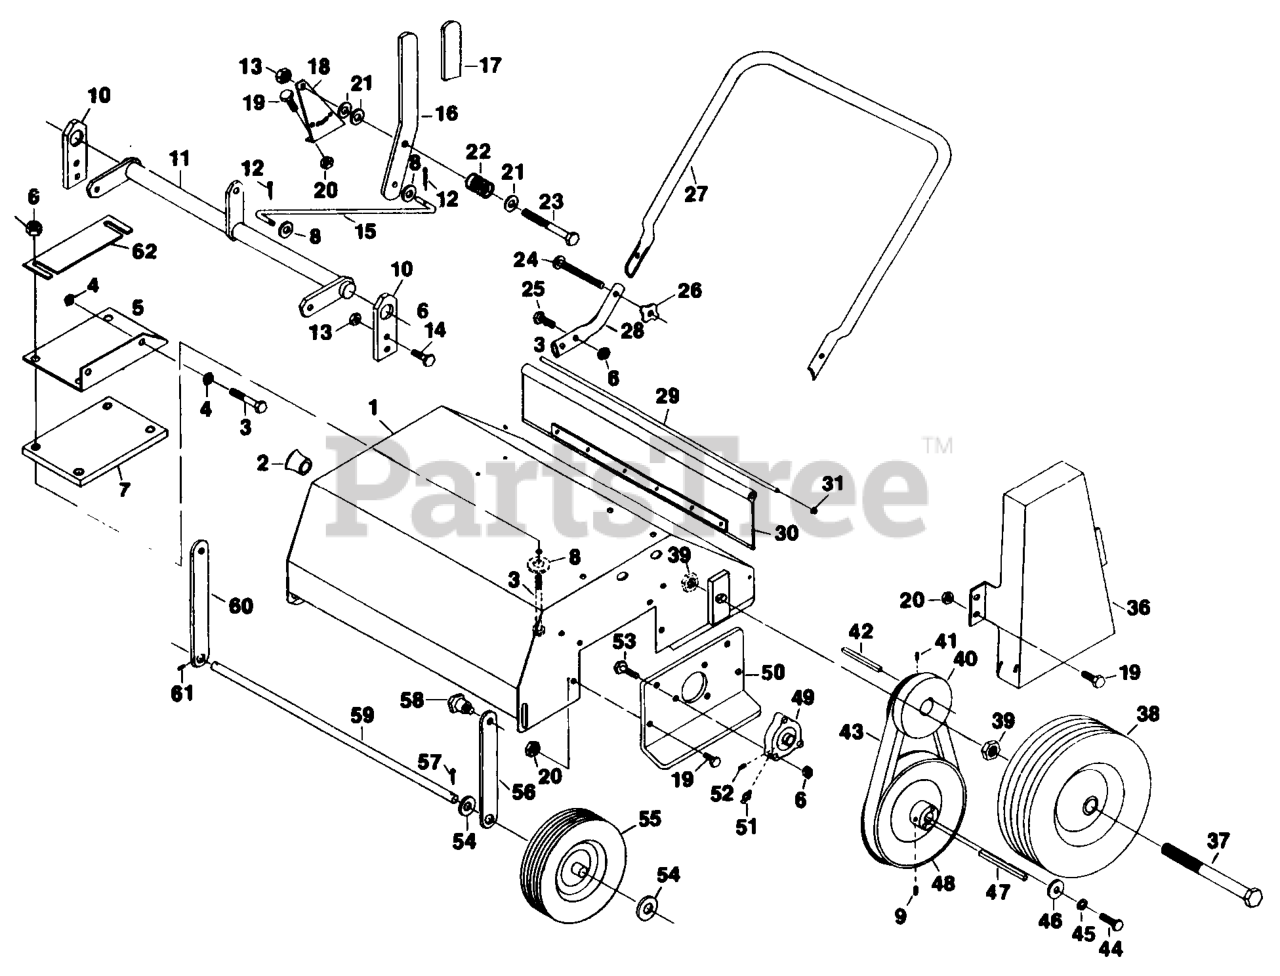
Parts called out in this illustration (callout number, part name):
9	SCREW-SET
12	PIN-COTTER
17	GRIP-LEVER
22	SPRING-COMPRESSION
31	NUT-PUSH
38	ASM,WHEEL & TIRE
43	BELT,RAKE
45	WASHER-LOCK
46	WASHER-RETAINER, PULLEY
55	ASM,WHEEL & TIRE
